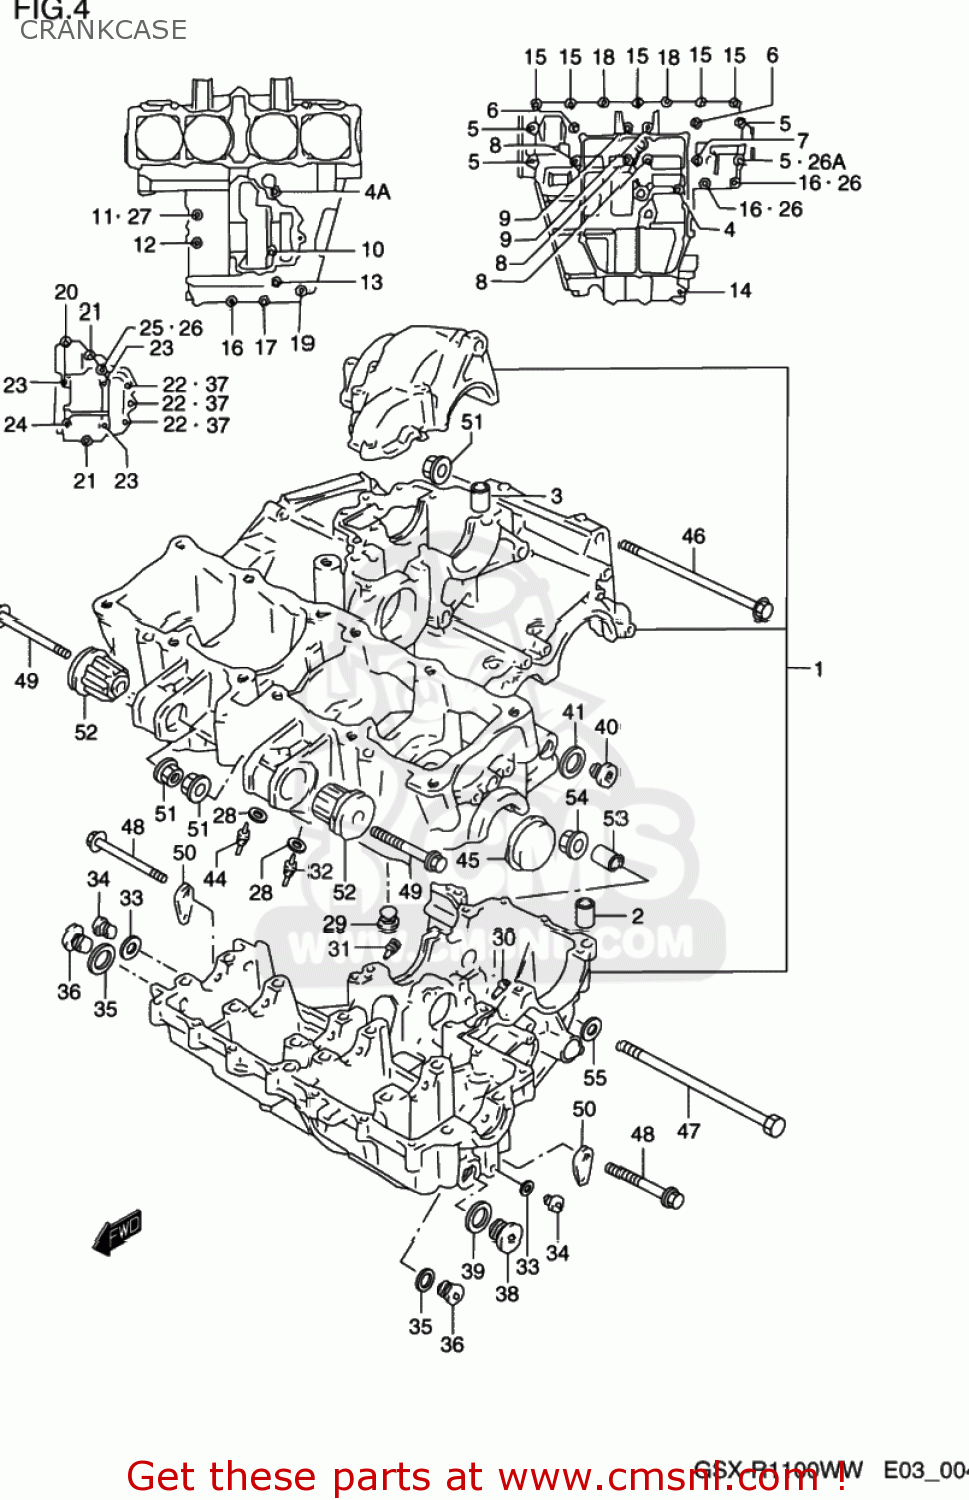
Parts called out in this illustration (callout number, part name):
1	CRANKCASE SET
2	PIN(10.4X13X22)
3	PIN
4	BOLT(6X105)
4A	BOLT(6X105)
5	BOLT 9X80
6	BOLT(9X95)
7	BOLT(9X105)
8	BOLT(9X115)
9	BOLT(9X60)
10	BOLT
11	BOLT
12	BOLT
13	BOLT
14	BOLT
15	BOLT
16	BOLT
17	BOLT
18	BOLT
19	BOLT
20	BOLT
21	BOLT
22	BOLT
23	BOLT
24	BOLT
25	BOLT(6X145)
26	GASKET(6.2X13X1.2) (NAS)
26A	GASKET(10.2X20X2).3 (NAS)
27	GASKET(8.2X14X1) (NAS)
28	O RING(D:1.2,ID:4)
29	PLUG,CRANKCASE,UPPER
30	JET
31	JET(140)
32	JET(13)
33	GASKET(10X14X3.6) (NAS)
34	PLUG(10X6.8)
35	GASKET(16X22X2) (NAS)
36	PLUG
37	GASKET(5.8X11X1.2) (NAS)
38	PLUG,22X11
39	GASKET(22X27X2) (NAS)
40	PLUG
41	GASKET(13.8X18.8X4.8) (NAS)
42	BEARING,CRANK THRUST(GREEN)
43	BEARING,CRANK THRUST(RED)
44	JET(13)
45	PLUG
46	BOLT 10X150
47	BOLT,ENGINE MOUNTING,REAR,LOWER
48	BOLT
49	BOLT
50	NUT,ENGINE MOUNT,LOWER
51	NUT
52	BUSH,ENGINE MOUNTING
53	SPACER,ENGINE MOUNT (L:13)
54	NUT 12MM
55	WASHER
